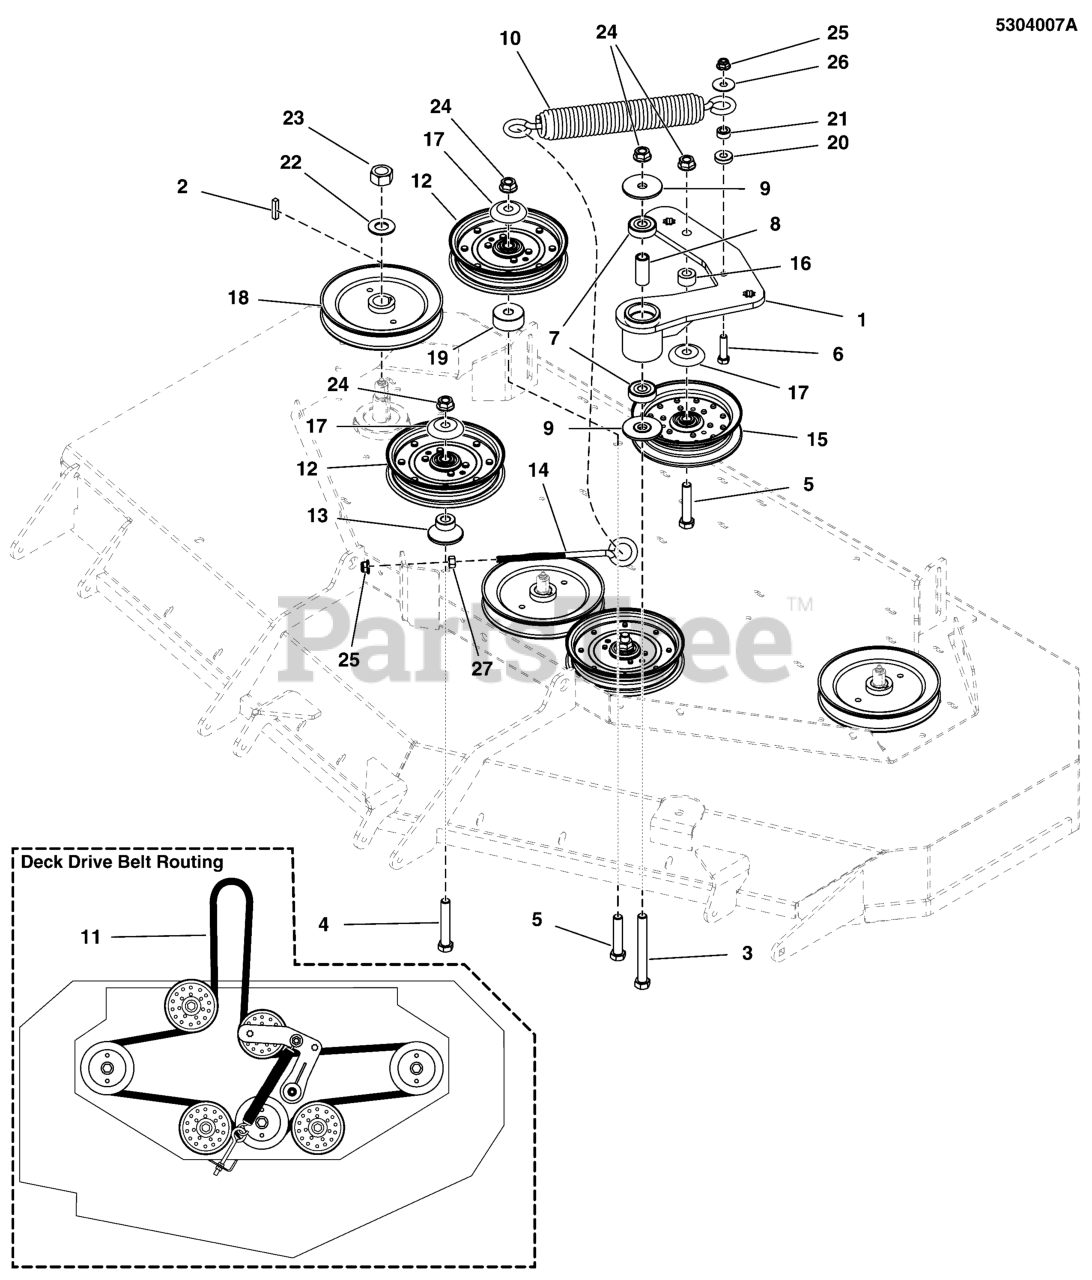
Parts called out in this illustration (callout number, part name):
1	WELD, IDLER ARM - BLK
2	KEY, 1/4 SQ X 1-1/4
3	BOLT, 1/2-13 X 4-1/2 GD5 CZ
4	BOLT, 1/2-13 X 3" GD5 CZ
5	BOLT, 1/2-13 X 2-1/2" GD5 CZ
6	BOLT, 3/8-16 X 1-1/2" GD5 CZ
7	BEARING, 6203-1/2", SEALED
8	SPACER, .510 X .750 X 1.749, CZ
9	SPACER, IDLER ARM, 1/2 X 2.25
10	SPRING, EXT, 1.5ODX12.25X.234WIRE BLK
11	BELT, 5V, 182.00"EL, LRG ARAMID, WRP, RC
13	IDLER MOUNT
14	EYE BOLT, 3/8-16 X 6, 3THRD, 1EYE, CZ
16	SPACER, .52 X 1.00 X .56, PM, CZ
17	SHIELD, PULLEY BEARING, CZ
18	PULLEY, 6.93 EOD X 25MM, SPLIT
19	SPACER, .51 X 1.75 X .75
20	SPACER, .39 X 1.00 X .25, PM, CZ
21	SPACER, .39 X .75 X .38, PM, CZ
22	WASHER, 3/4 BELLEVILLE
23	NUT, 3/4-16 HEX
24	NUT, Hex Flange, Nylock, 1/2-13
25	NUT, 3/8-16 HEX NYLOCK FLANGE
26	WASHER-3/8 FENDER
27	NUT, 3/8-16 HEX
